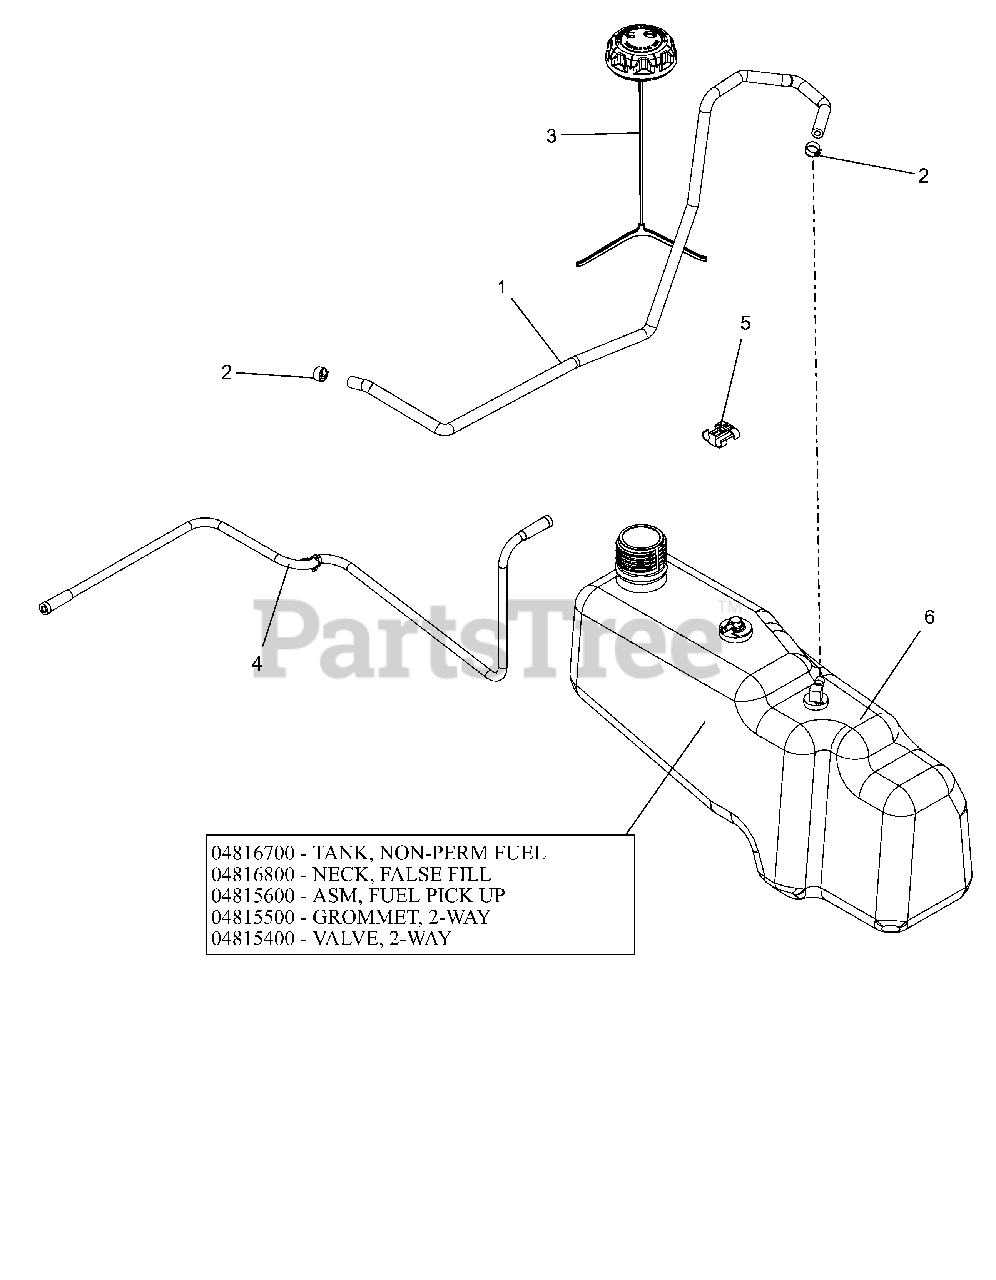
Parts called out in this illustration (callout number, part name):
1	HOSE, .25 LOW-PERM BULK GAS
2	CLAMP, FUEL LINE
3	CAP, FUEL VENT-IN 2.25" RATCH.
4	LINE, FUEL VENT KAWI
5	CLIP, T, .38-.50
6	ASM,TANK NON-PERM FUEL
6	TANK, ZOOM/ZT NON-PERM, FUEL
6	NECK, FALSE FILL ZOOM/ZT
6	ASM, FUEL PICK-UP ZOOM/ZT 2015
6	GROMMET, 2-WAY
6	VALVE, 2-WAY
